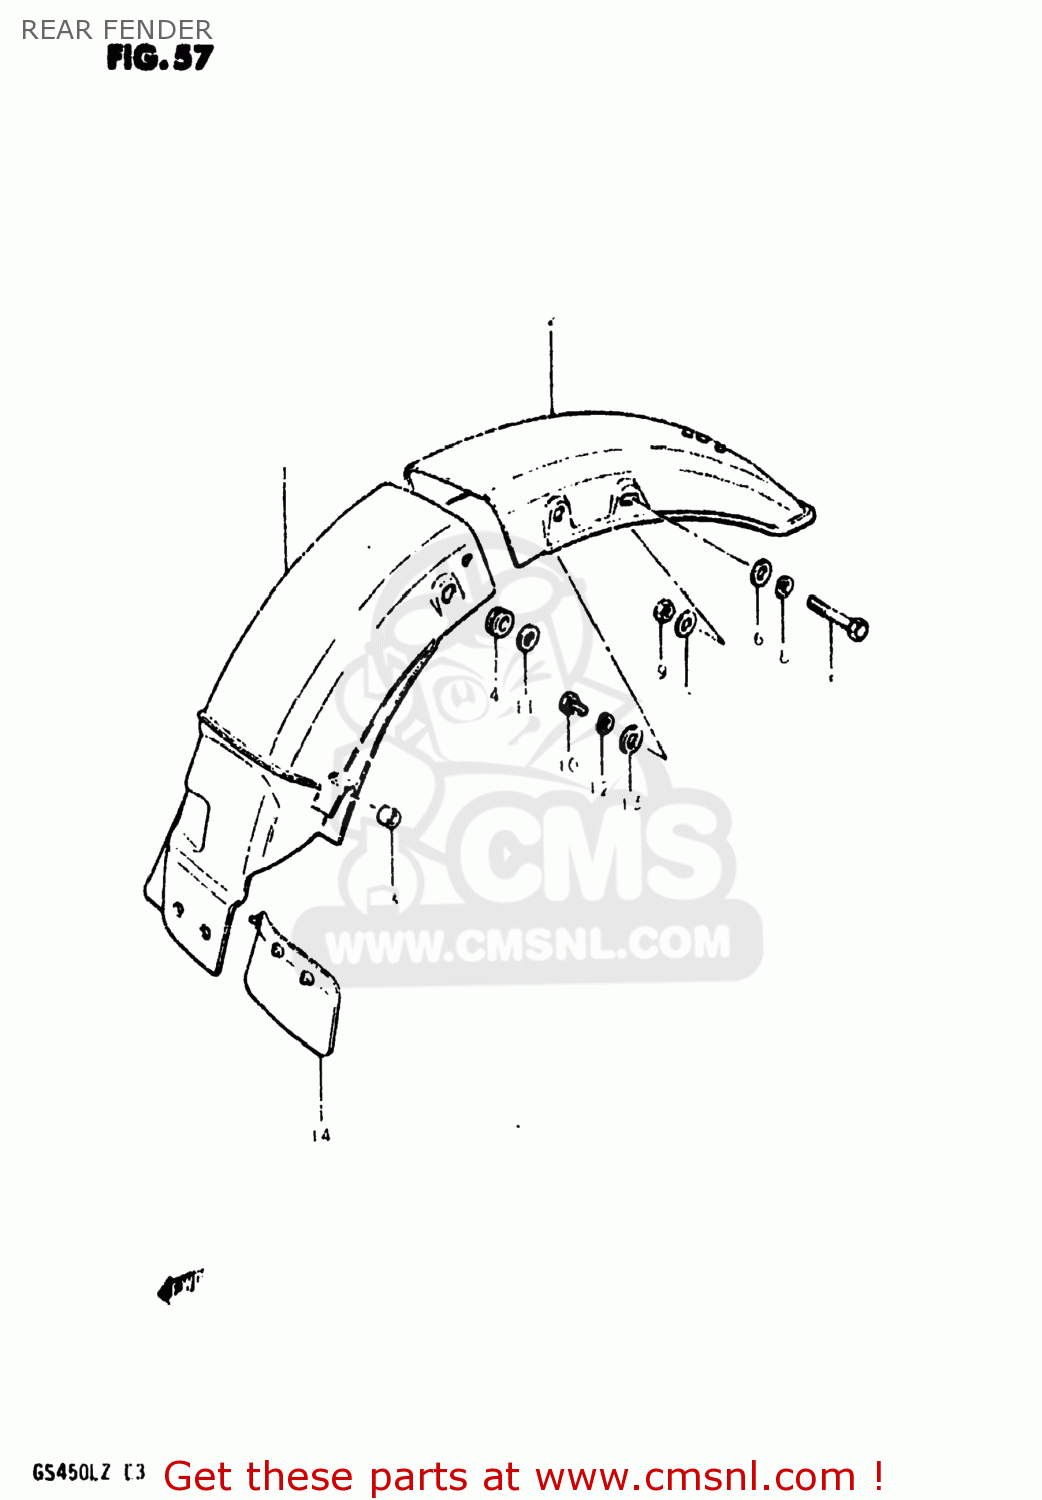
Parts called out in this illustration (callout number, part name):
1	BODY,REAR FENDER,FRONT
2	FENDER,REAR
3	CUSHION
4	CUSHION
5	BOLT
6	WASHER
7	WASHER
8	LOCK WASHER
9	NUT
10	BOLT 8X12
11	WASHER
12	LOCK WASHER
13	WASHER
14	GUIDE,RR FENDER MUD
